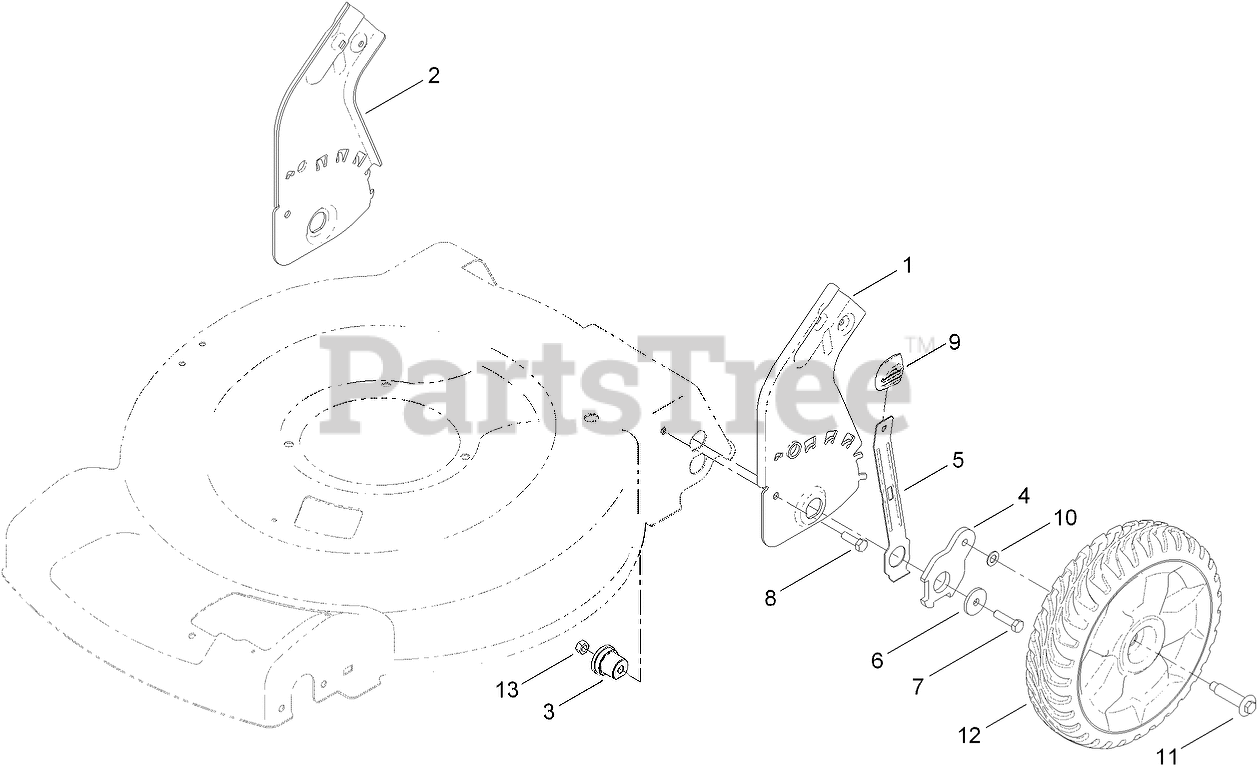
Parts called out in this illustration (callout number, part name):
1	PLATE-HOC, REAR (LH)
2	PLATE-HOC, REAR (RH)
3	BUSHING-MOUNT, HOC
4	ARM-PIVOT, REAR
5	ARM-SPRING, REAR
6	Washer-Flat
7	SCREW-HH
8	SCREW-HH
9	Knob-Lever, HOC
10	WASHER
11	BOLT-SHOULDER
12	11 INCH WHEEL ASM
13	NUT-LOCK, NI
